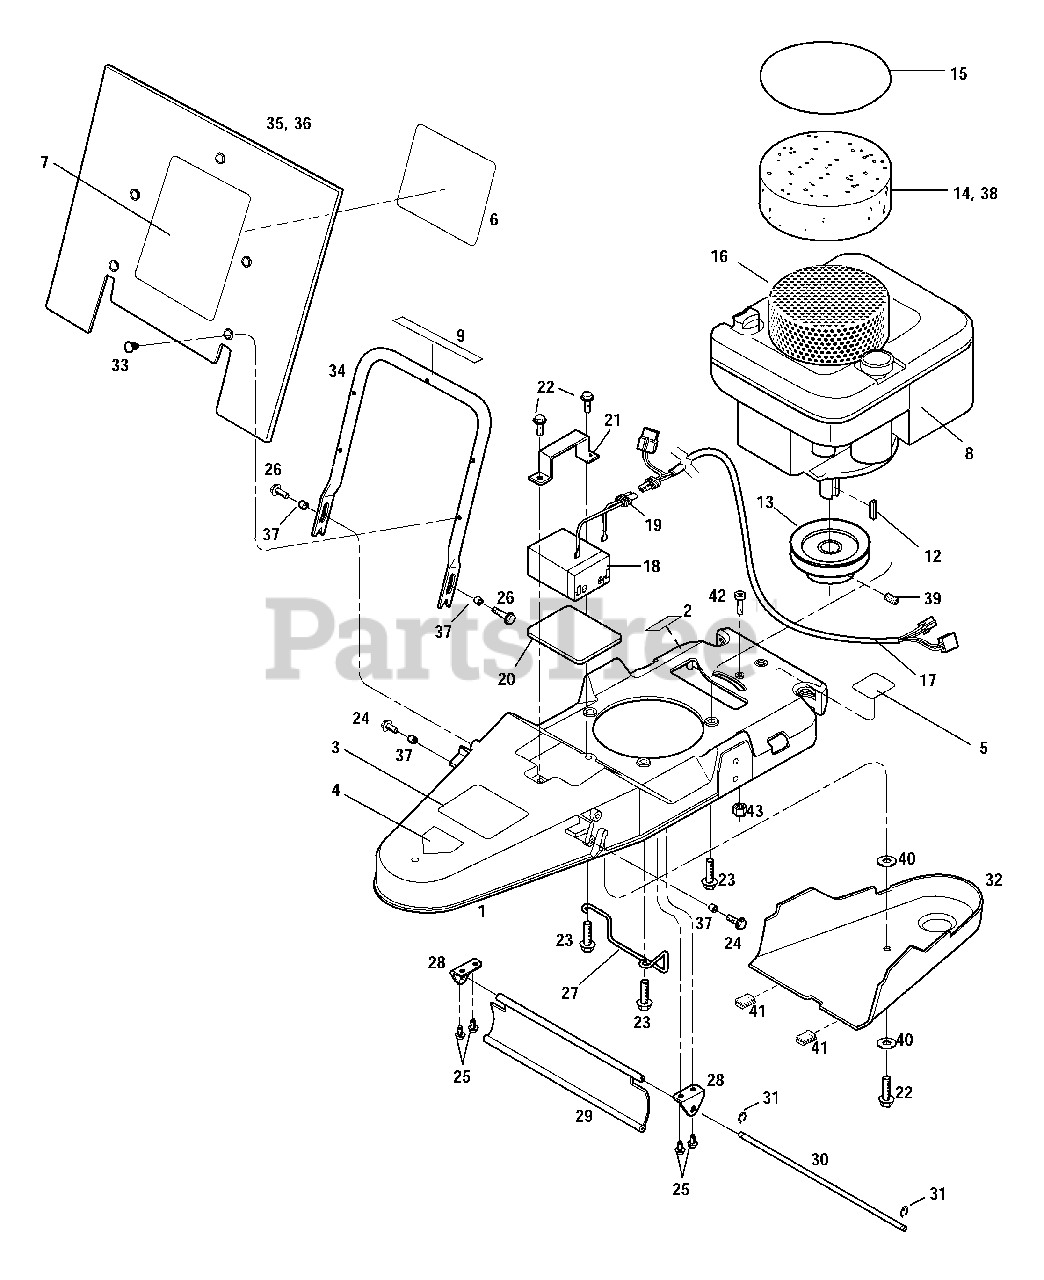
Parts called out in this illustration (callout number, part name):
1	Deck with decals
2	Decal-Hot Surface
3	Decal-Warning/Thrown Objects
4	Decal-Danger Feet/Hands
5	Decal-Warning
6	Decal-Warning
7	Decal-Logo
8	Engine-Quantum, Std
9	Decal - Cover Support
12	Key, 3/16" x 1" Sq.
13	Pulley, 4" OD
14	Engine Debris Guard/Foam
15	O-Ring/Engine Debris Guard
16	Engine Debris Guard
17	Wire Harness
18	Battery
19	Battery Connector
20	Battery Pad Model 52052
21	Battery Bracket
22	Hex Hd. Flange Screw, 5/16-18 x 1
23	Hex Hd. Flange Screw, 3/8-16 x 1-1/2
24	Hex Hd Flange Screw, 1/4-20 x 3/4
25	Hex Hd Flange Screw, 1/4-20 x 5/8
26	Hex Hd Flange Screw, 1/4-20 x 1
27	Belt Guide
28	Flap Bracket
29	Deflector Shield
30	Deflector Shield Rod
31	E-Ring, 5/16"
32	Belt Cover
33	Push-In Fastener
34	Engine Cover Support w/decal
35	Engine Cover w/decals
36	Engine Cover w/decals
37	Spacer
38	Service Kit
39	Set Screw
40	Washer
41	Clip
42	Socket Hd. Capscrew, 1/4-20 x 1
43	Toplock Nut, 1/4-20
